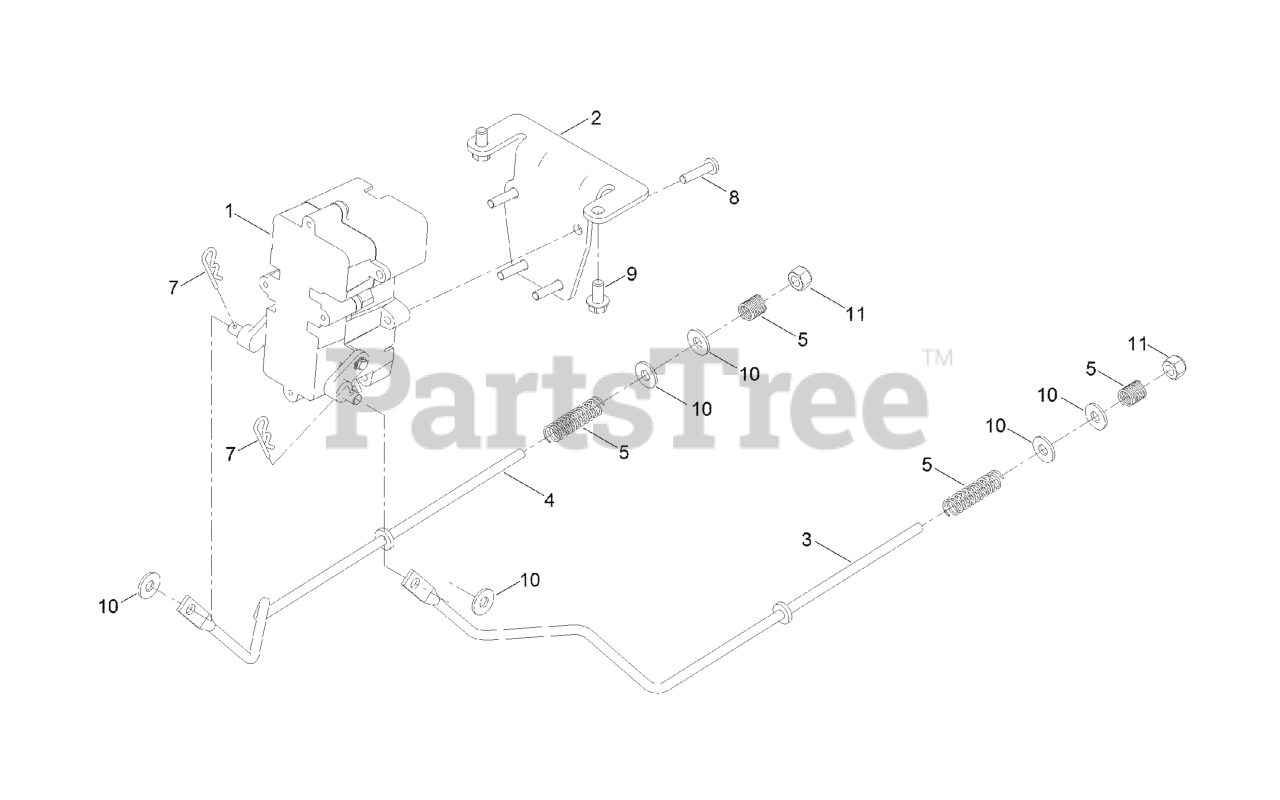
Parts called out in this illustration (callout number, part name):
1	BRAKE BOX ASM
2	BRACKET-MOUNT, BRAKE
3	ROD-BRAKE, LH
4	ROD-BRAKE, RH
5	SPRING-COMPRESSION
8	SCREW-PPH
9	SCREW-HWH
11	NUT-LOCK, NI
